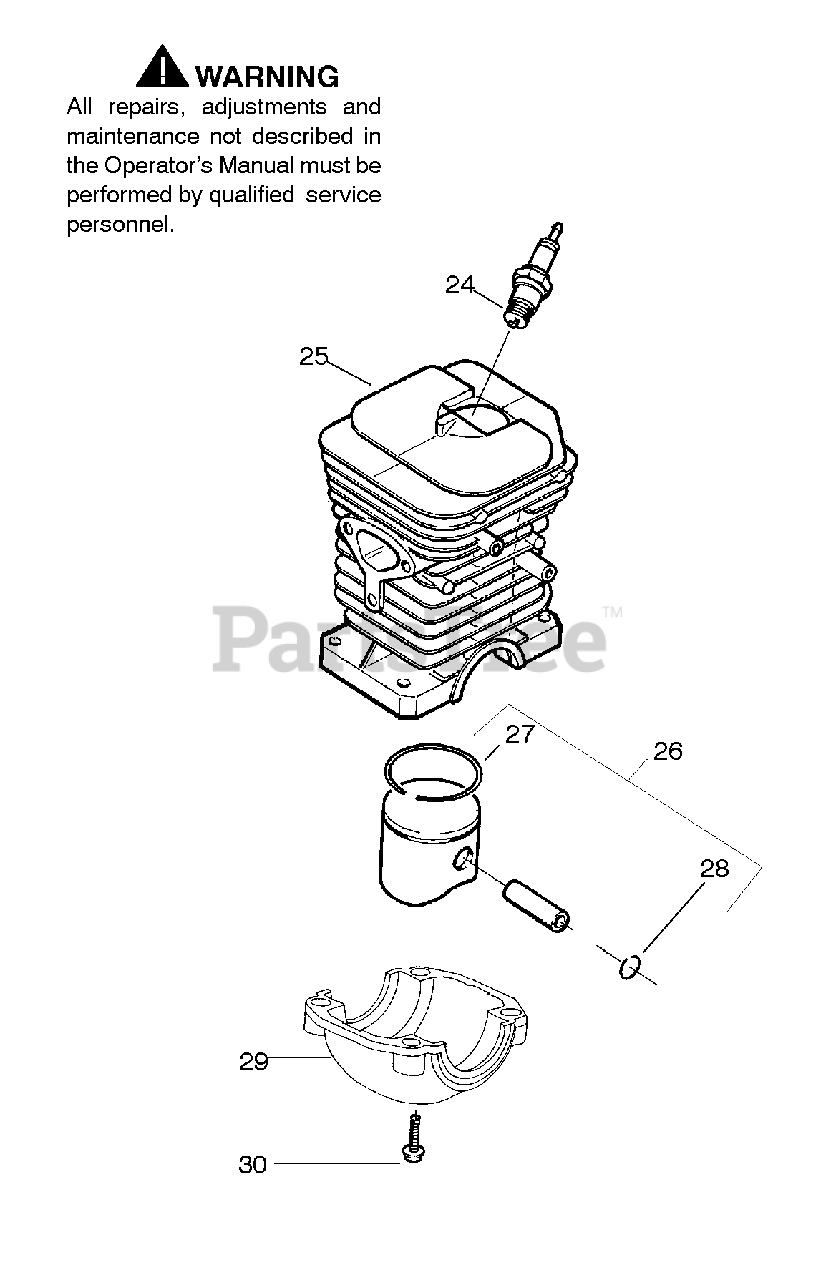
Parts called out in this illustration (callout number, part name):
24	Spark Plug (RCJ-7Y)
25	Kit-Cylinder (40cc)
26	Kit-Piston (40cc)
27	Ring-Piston (40cc)
28	Piston Pin Retainer
29	Cap-Crankcase
